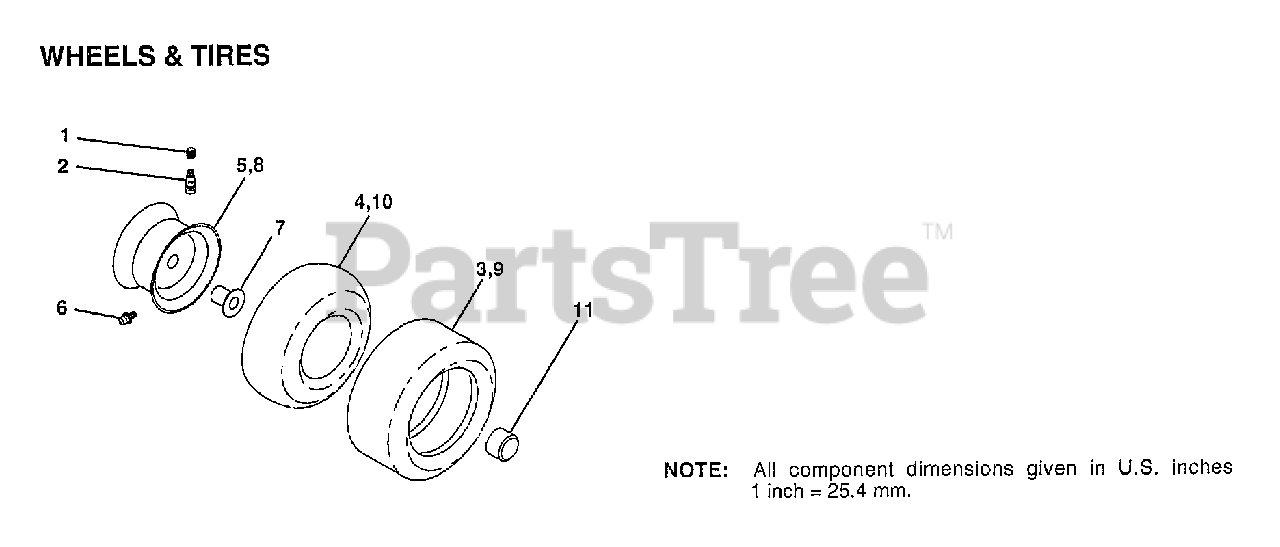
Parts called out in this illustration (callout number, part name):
1	Valve Cap
2	VALVE STEM LT
4	TUBE.5.3/4.5/6
5	"RIM ASM 6"" FRT"
6	FITTING LT
7	"FLANGE, BEARING"
8	"RIM AS 8"" REAR"
9	TIRE.20X8-8
10	TUBE.18X9.5-8
11	HUB CAP
